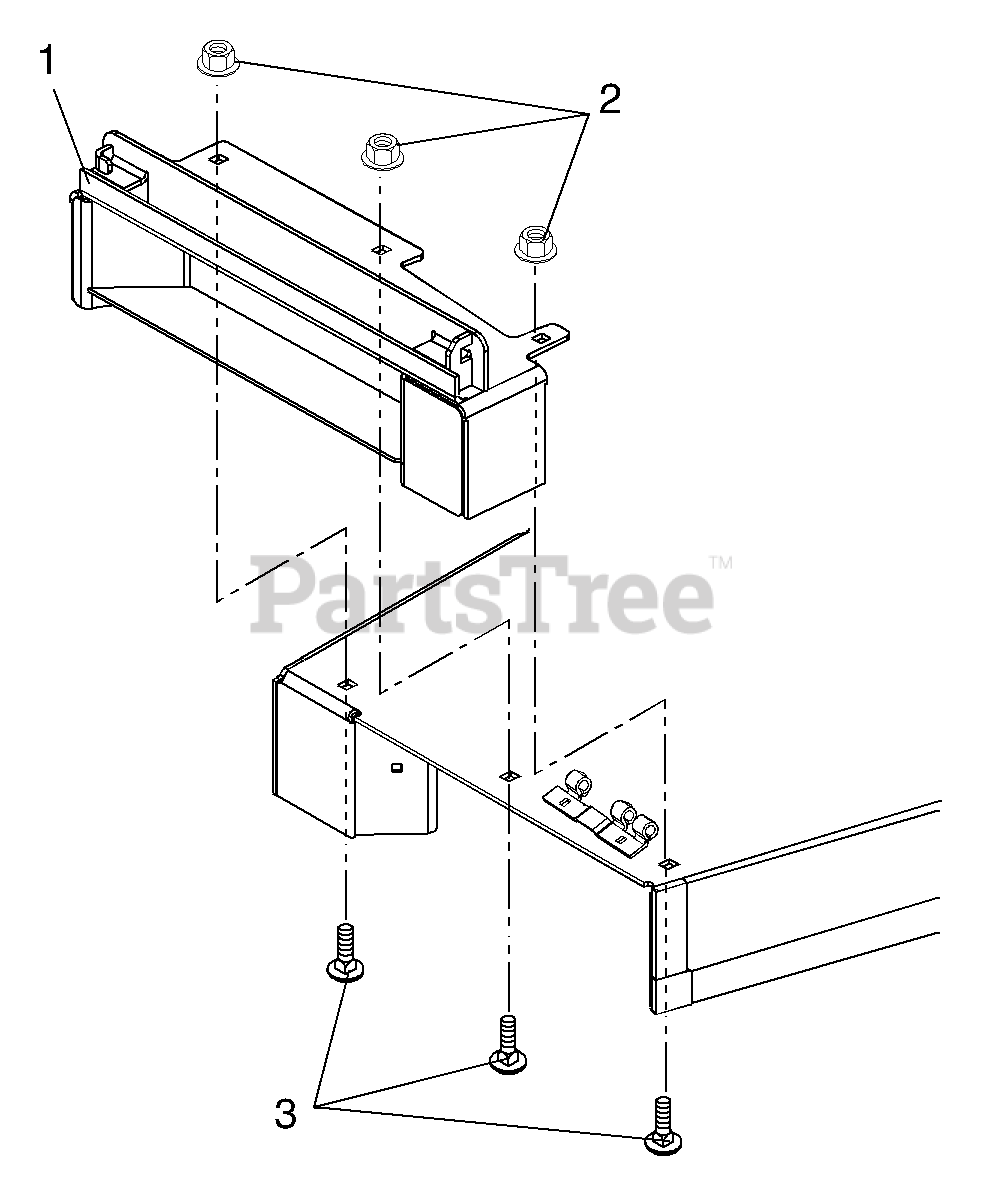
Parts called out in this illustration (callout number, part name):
1	Bagger Extension Bracket
2	Top-Locking Flange Nut, 3/8"-16 Grade 5
3	Round Head Square Neck Bolt, 3/8"-16 x 3/4" Grade 5
